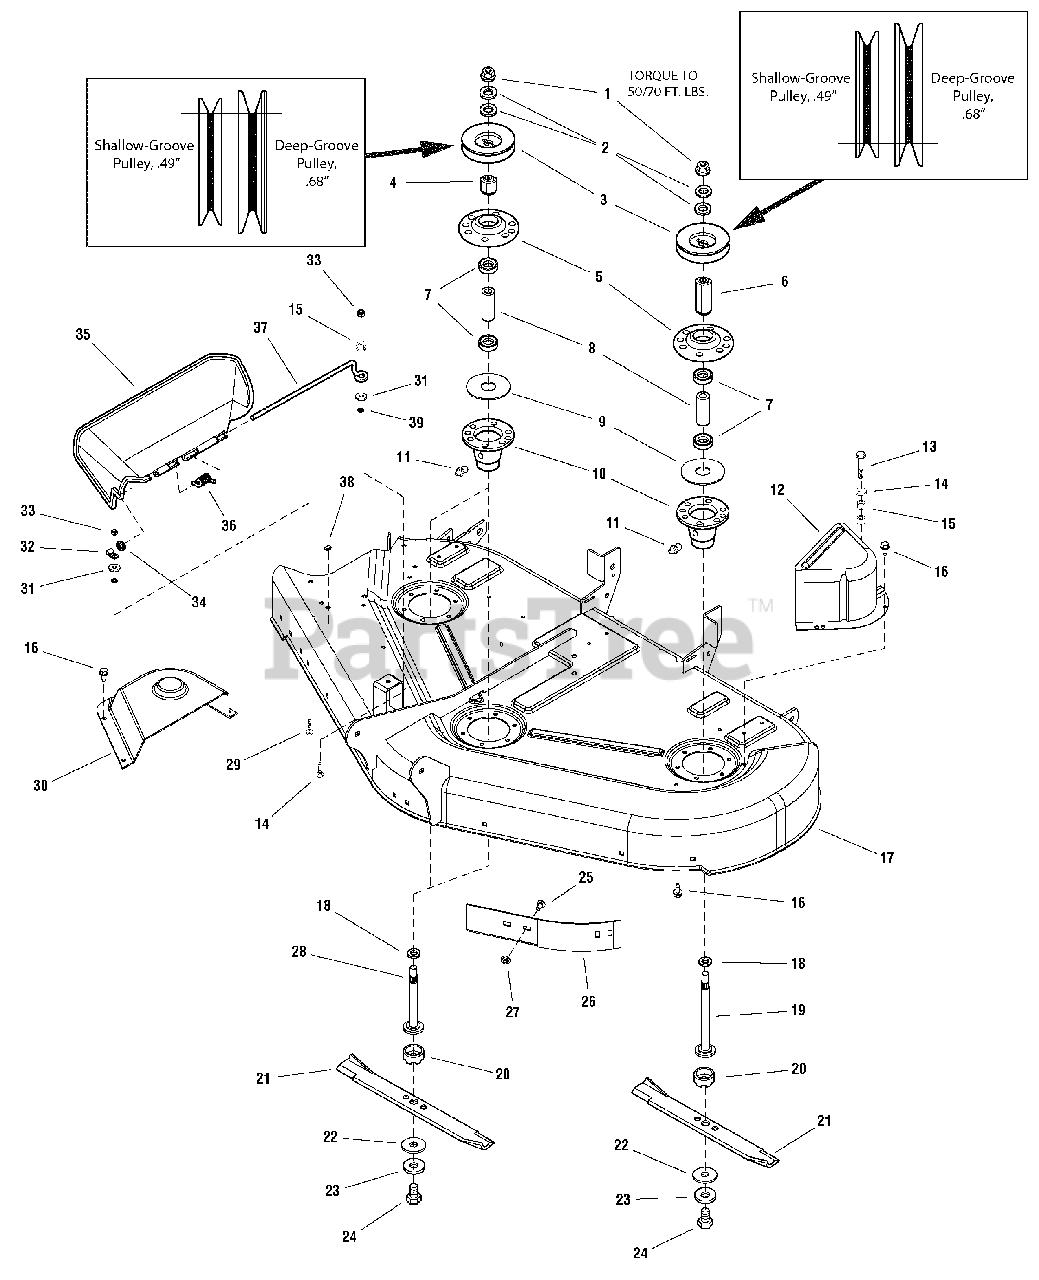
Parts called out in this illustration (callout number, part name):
1	NUT, Hex, Flange, 9/16-8
2	WASHER, Belleville
3	PULLEY, RH Arbor & LH Arbor, 4-1/2, .49" Shallow-Groove
4	HUB, Pulley, RH
5	COVER, Arbor Housing
6	HUB, Adapter, LH
7	BEARING
8	SPACER
9	GASKET, Foam
10	HOUSING ASSEMBLY, Arbor Bottom, w/Lube Fitting
11	FITTING, Grease
12	COVER, Arbor
13	CAPSCREW, Hex Head, Serrated Flange Taptite, 5/16-18 x 2 G5
14	CARRIAGE BOLT, 1/4-20 x 1-1/2, Black
15	NUT, 1/4-20, Hex
16	CAPSCREW, Hex Head, Taptite, 5/16-18 x 3/4
17	HOUSING ASSEMBLY, 50" (Orange)
17	HOUSING ASSEMBLY, 50" (Red)
18	WASHER
19	SHAFT, Arbor
20	SHIELD, Grass, Lower
21	BLADE, 18-1/8, 50" Deck
22	WASHER, Hex
23	WASHER, Spring
24	CAPSCREW, Hex Head, 7/16-14 x -1/4
25	BOLT, Carriage, 5/16-18 x 3/4
26	BAFFLE, Anti-Blowout
27	NUT, Hex, Flange Whizlock, 5/16-18
28	SHAFT, Arbor, RH
29	CARRIAGE BOLT, 1/4-20 x 1, Black
30	COVER, Arbor, RH
31	WASHER, Plain, 1/4 (6 Total for Export)
32	CLAMP
33	NUT, Hex Lock, ESNA, 1/4-20
34	WASHER, Flat, 5/16
35	DEFLECTOR, Plastic
36	SPRING
37	ROD, Deflector, Front
38	PLUG, Plastic
39	NUT, Push On
